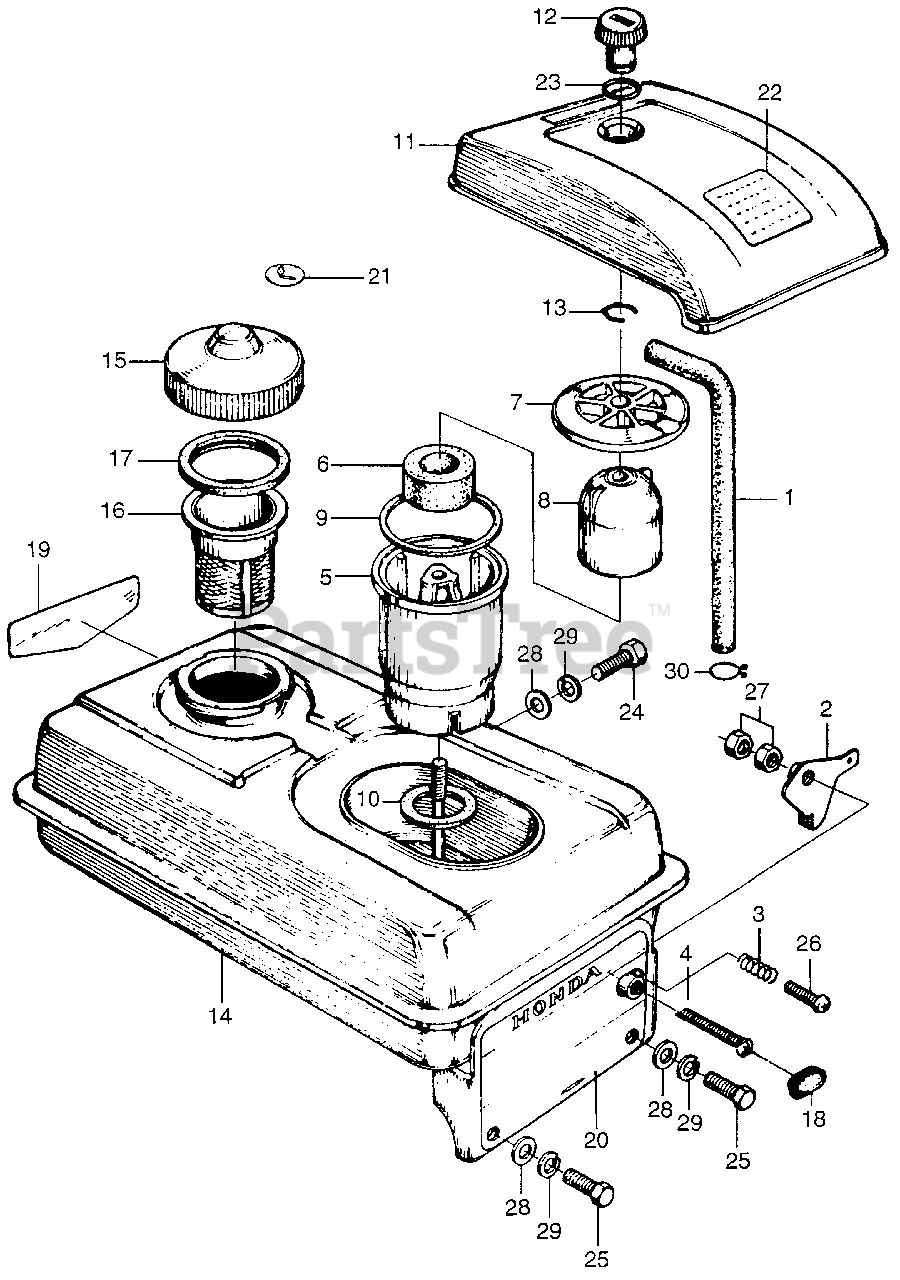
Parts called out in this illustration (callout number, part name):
1	PIPE, BREATHER (NOT AVAILABLE)
2	GUIDE, CONTROL (NOT AVAILABLE)
3	SPRING, STOPPER (NOT AVAILABLE)
4	SCREW, PAN (6X65)
5	PAN, AIR CLEANER OIL
6	ELEMENT, AIR CLEANER
7	SEPARATOR A (NOT AVAILABLE)
8	SEPARATOR B
9	GASKET A, CLEANER (NOT AVAILABLE)
10	GASKET B, CLEANER (NOT AVAILABLE)
11	COVER, AIR CLEANER *NH31* (MCKINLEY WHITE) (NOT AVAILABLE)
12	NUT, CLEANER CAP
12	NUT, CLEANER CAP (NOT AVAILABLE)
13	CLIP, CLEANER (NOT AVAILABLE)
14	TANK FUEL *NH31* (MCKINLEY WHITE) (NOT AVAILABLE)
15	CAP, FUEL TANK (NOT AVAILABLE)
16	FILTER, FUEL
17	GASKET, FUEL FILTER (NOT AVAILABLE)
20	PLATE, CAUTION
21	MARK, TANK CAP CAUTION (NOT AVAILABLE)
22	PLATE, CAUTION (NOT AVAILABLE)
23	O-RING (11.5X2)
24	BOLT, HEX. (6X20)
25	BOLT, HEX. (6X16)
26	SCREW, PAN (4X12)
27	NUT, HEX. (6MM)
28	WASHER, PLAIN (6MM)
29	WASHER, SPRING (6MM)
30	CLIP, TUBE (B12)
